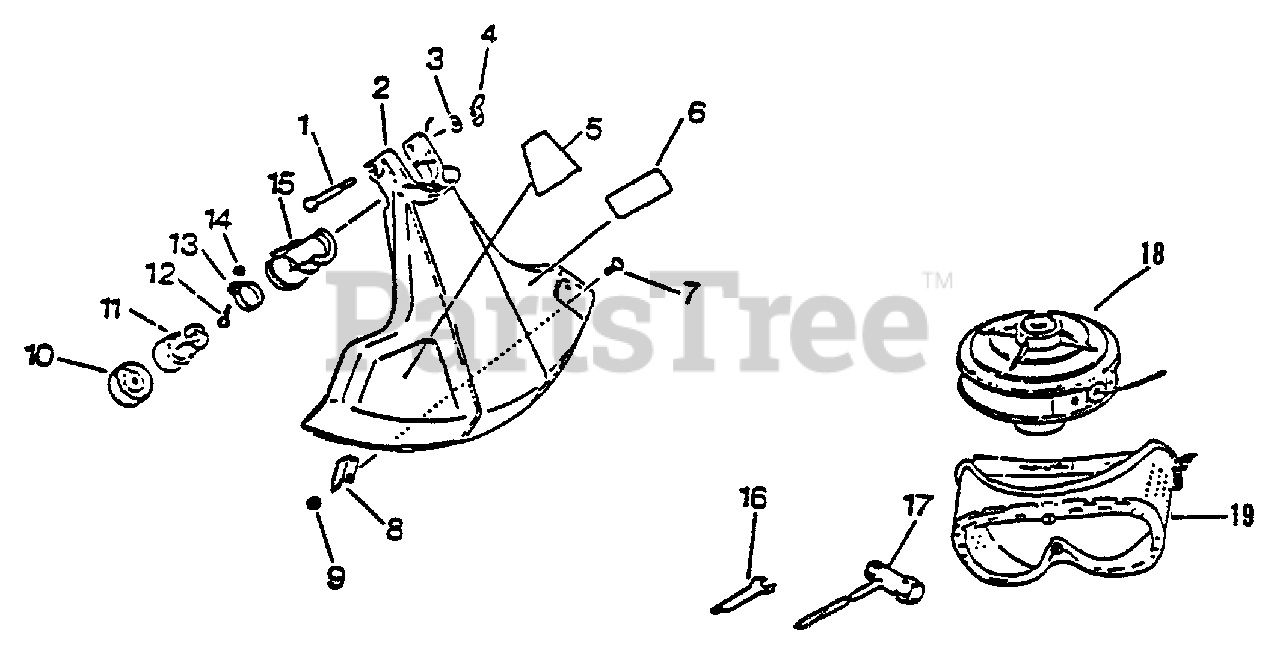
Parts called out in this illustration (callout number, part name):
1	BOLT - 6X50
2	DEBRIS SHIELD KIT
3	WASHER - 6
4	WINGNUT - 6
5	LABEL - CAUTION
6	LABEL - ECHO
7	SCREW - 5X16
8	KNIFE, TRIMMER LINE
10	ADAPTOR, BLADE - UPPER
11	GEAR CASE ASSY
12	SCREW - 5X10
15	BRACKET, BEARING CASE
16	SPANNER - 10mm
17	T-WRENCH - 8X19mm
18	KNIFE, TRIMMER LINE
